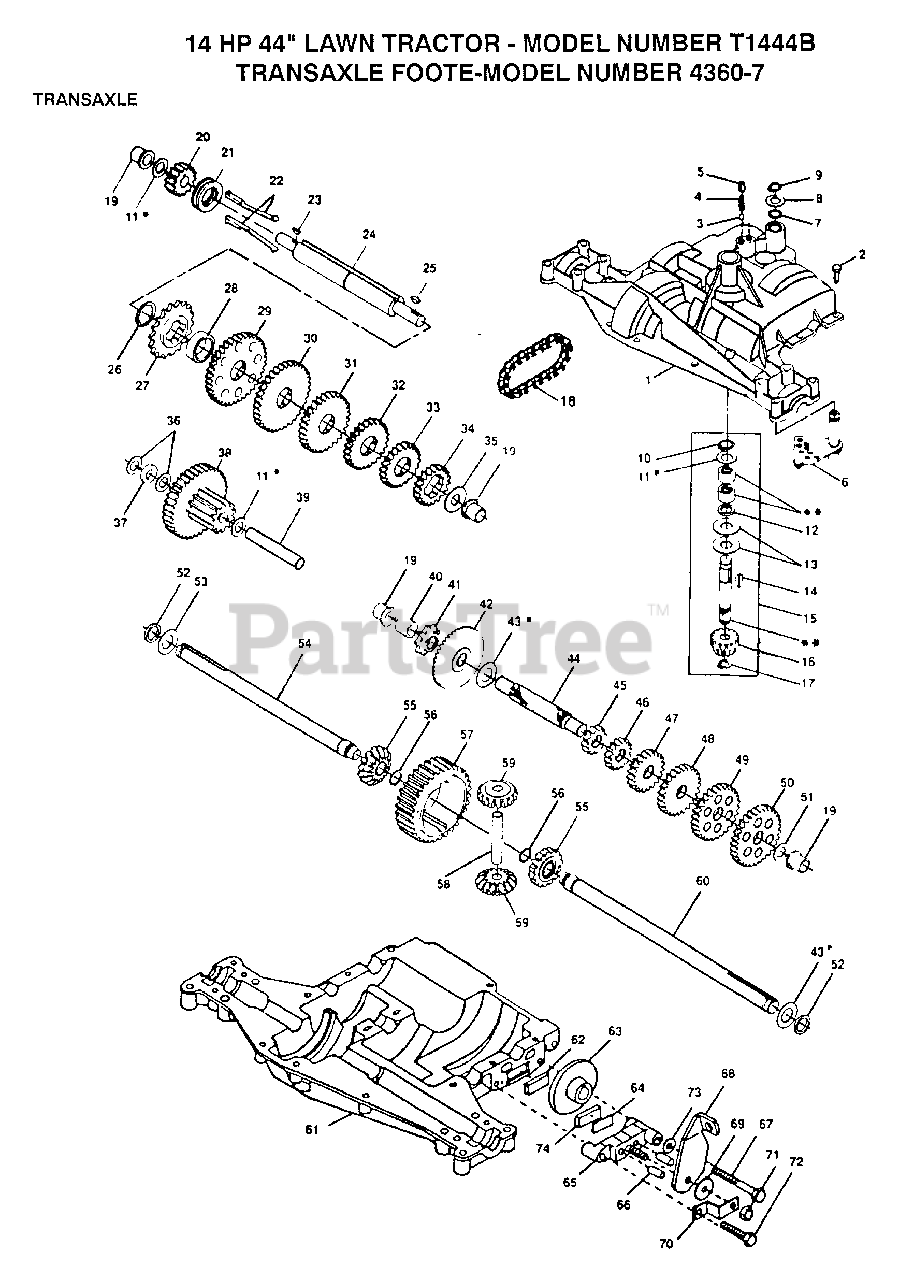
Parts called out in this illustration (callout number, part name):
1	HOUSING UPPER
3	BALL DETENT
4	SPRING, DETENT
5	SCREW, SET
6	ASSY SHIFTER
8	WASHER PLAIN
8A	WASHER PLAIN
8B	WASHER PLAIN
8C	WASHER PLAIN
8D	WASHER PLAIN
8E	WASHER PLAIN
8F	WASHER PLAIN
9	RING RETAINING
10	RING RETAINING
11	WASHER PLAIN
11A	WASHER PLAIN
11B	WASHER, PLAIN .632 X 1.00 X .026
11C	WASHER PLAIN
11D	WASHER PLAIN
11E	WASHER PLAIN
11F	WASHER PLAIN
11G	WASHER PLAIN
11H	WASHER, PLAIN .632 X 1.00 X .060
11I	WASHER PLAIN
13	WASHER, PLAIN .632 X 1.38 X .046
14	KEY WOODRUFF #9
15	ASSY KIT INPUT SHAFT
16	PINION, BEVEL, 14 TEETH
17	RING, RETAINING
18	CHAIN, 24 PITCHES
19	BEARING, FLANGE
20	GEAR SPUR, 14 TEETH
21	COLLAR CLUTCH
22	KEY CLUTCH
23	KEY WOODRUFF #3
24	SHAFT INTERMEDIATE
25	KEY, WOODRUFF, #61
26	RING, RETAINING
27	SPROCKET, 18 TEETH
29	GEAR, SPUR, 37 TEETH
30	GEAR, SPUR, 35 TEETH
31	GEAR, SPUR, 30 TEETH
32	GEAR, SPUR, 25 TEETH
33	GEAR, SPUR, 22 TEETH
35	WASHER, PLAIN .640 X 1.37 X .061
36	WASHER, PLAIN .632 X 1.00 X .026
37	SPACER .630 X 1.00 X .169
38	ASSY GEAR COMB 12&35 TEETH
39	SHAFT IDLER
40	SPACER .635 X .875 X .755
41	SPROCKET, 9 TEETH
42	GEAR, BEVEL, 42 TEETH
43	WASHER PLAIN
43A	WASHER PLAIN
43B	WASHER PLAIN
43C	WASHER PLAIN
43D	WASHER PLAIN
43E	WASHER PLAIN
43F	WASHER, PLAIN .758 X 1.25 X .031
43G	WASHER PLAIN
43H	WASHER PLAIN
43I	WASHER PLAIN
43J	WASHER PLAIN
43K	WASHER PLAIN
43L	WASHER PLAIN
44	SHAFT, DRIVE
45	GEAR, SPUR, 12 TEETH
46	GEAR SPUR, 15 TEETH
47	GEAR, SPUR, 20 TEETH
48	GEAR, SPUR, 25 TEETH
49	GEAR, SPUR, 28 TEETH
50	GEAR, SPUR, 31 TEETH
51	WASHER, PLAIN .632 X 1.00 X .060
53	WASHER PLAIN
54	AXLE LEFT HAND
55	GEAR, MITER, 15 TEETH
56	RING, RETAINING
57	GEAR, SPUR, 32 TEETH
58	SHAFT, CROSS
59	GEAR, MITER, 15 TEETH
60	AXLE, R.H.
61	HOUSING LOWER
62	PUCK, FRICTION
63	DISC, BRAKE
65	JAW, BRAKE
66	PIN, DOWEL
67	SCREW TAPPING
68	LEVER, ACTUATING
69	WASHER, PLAIN .321 X 1.00 X .055
70	BRACKET, ANTI-ROTATION
71	LOCKNUT 5/16-24
72	SCREW TAPPING
73	WASHER PLAIN
74	PUCK, FRICTION
